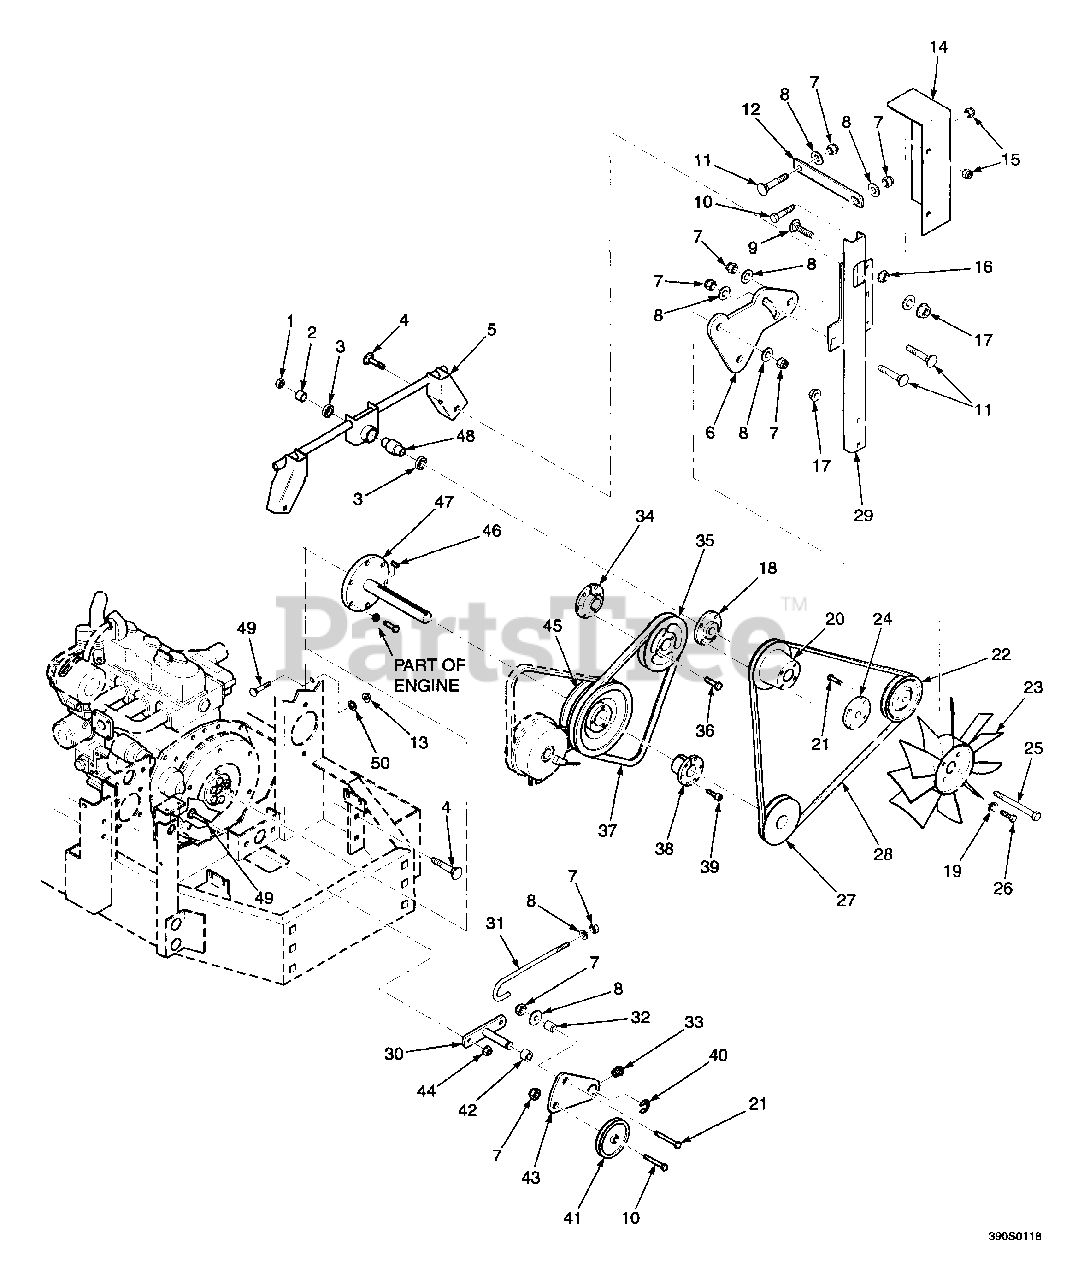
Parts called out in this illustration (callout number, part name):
1	Hex Locknut, 1/2-20
2	Spacer, Fan
3	Bearing
4	Carriage Bolt, 1/2-13 x 1-1/4
5	Bracket, Fan Mounting
6	Idler Bracket, Fan Drive
7	Hex Locknut, Elastic Stop, 3/8-16
8	Flat Washer, 3/8 (.391 x .938 x .105)
9	Carriage Bolt, 1/4-20 x 1
10	Bolt, Hex Head, 3/8-16 x 1-1/4
11	Carriage Bolt, 3/8-16 x 1-1/4
12	Brace, Fan Support
13	Serr. Fl. Hex Nut, 1/4-20
14	Guard, Pump Belt
15	Hex Locknut, Elastic Stop, 1/4-20
16	Carriage Bolt, 5/16-18 x 3/4
17	Serr. Fl. Hex Nut, 1/2-13
18	Hub, Fan
19	Lockwasher, 1/4
20	Pulley, Fan
21	Bolt, Hex Head, 3/8-18 x 1-3/4
22	Pulley, Belt Tensioning Idler
23	Fan
24	Hub, Fan
25	Bolt, Hex Head, 1/2-20 x 4.75, LH Thread
26	Bolt, Hex Head, 1/4-28 x 1
27	Pulley, 4.25 O.D. x 1.4375 I.D.
28	Belt, Fan Drive
29	Upright, Fan Support - RH
30	Base, Idler Pivot - Pump
31	Rod, J-Hook
32	Spacer, J Pull Rod
33	Grease Fitting
34	Taper Hub, .75 Bore
35	Pulley, Pump, 5.94 O.D.
36	Bolt, Hex Head, 1/4-20 x 3/8
37	Belt, Pump Drive
38	Taper Hub, 1-7/16 Bore
39	CPSCR, Socket Head, 1/4-20 x 1-1/4
40	Retaining Ring, .75 Ext
41	Pulley, Idler, 5.95 O.D.
42	Bushing, Oilite - .75 I.D.
43	Arm, Idler
44	Serr. Fl. Hex Nut, 5/16-18
45	Pulley, Double Groove
46	Key, 3/8 x 1-1/4
47	Stubshaft, Crankshaft
48	Spacer
49	Carriage Bolt, 5/16-18 x .75
50	Flatwasher, 1/4
